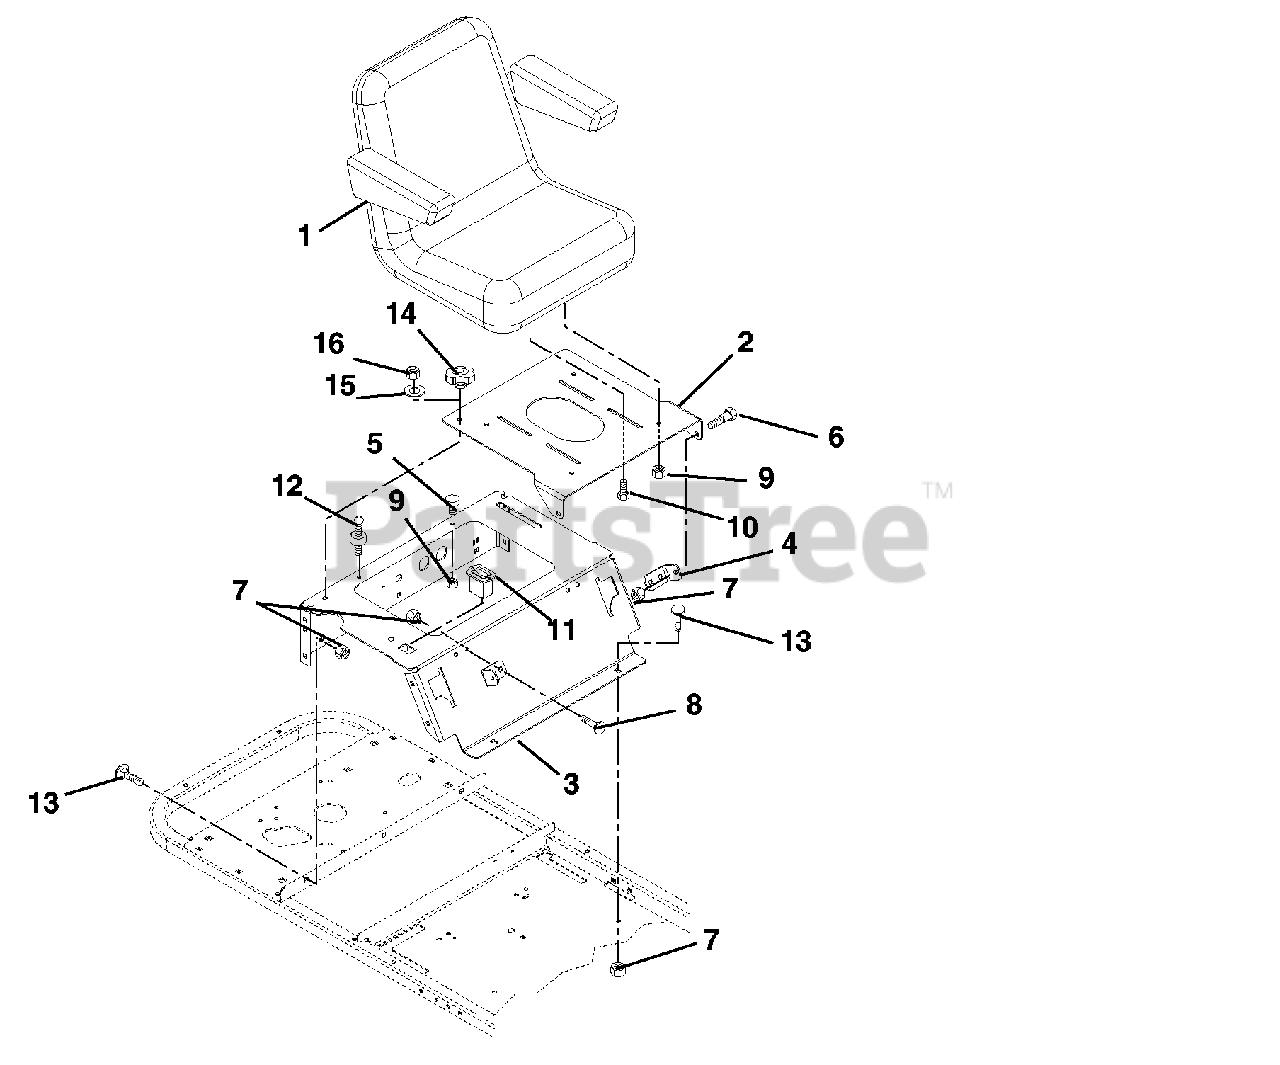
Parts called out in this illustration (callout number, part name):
1	SEAT, TS2800 MICHIGAN W/ARM.
2	SEAT PLATE
3	SEAT SUPPORT
4	BKT-SEAT PLATE
5	BUMPER, RUBBER
6	BOLT-SHLDR .375-16X.150
7	NUT-LK-TOP-FLG .38-16 BLKZC
8	BLT-RDHDSQNK .38-16X.75 G5BZ
9	@NUT-SPNLK-FLG .312-18 YWZC
10	BLT-SERHFWH .31-18 X 1 YWZC
11	HOURMETER-QUARTZ 80VDCMAX
12	BUMPER, STUD
13	BLT-RDHDSQNK .38-16X.75 G5BZ
14	KNOB-CLAMPING, .312-18 NYLOC
15	WSHR-FL-STL .328X1.0X.094 YWZC
16	@NUT-LK-NYL .312-18 YWZC
